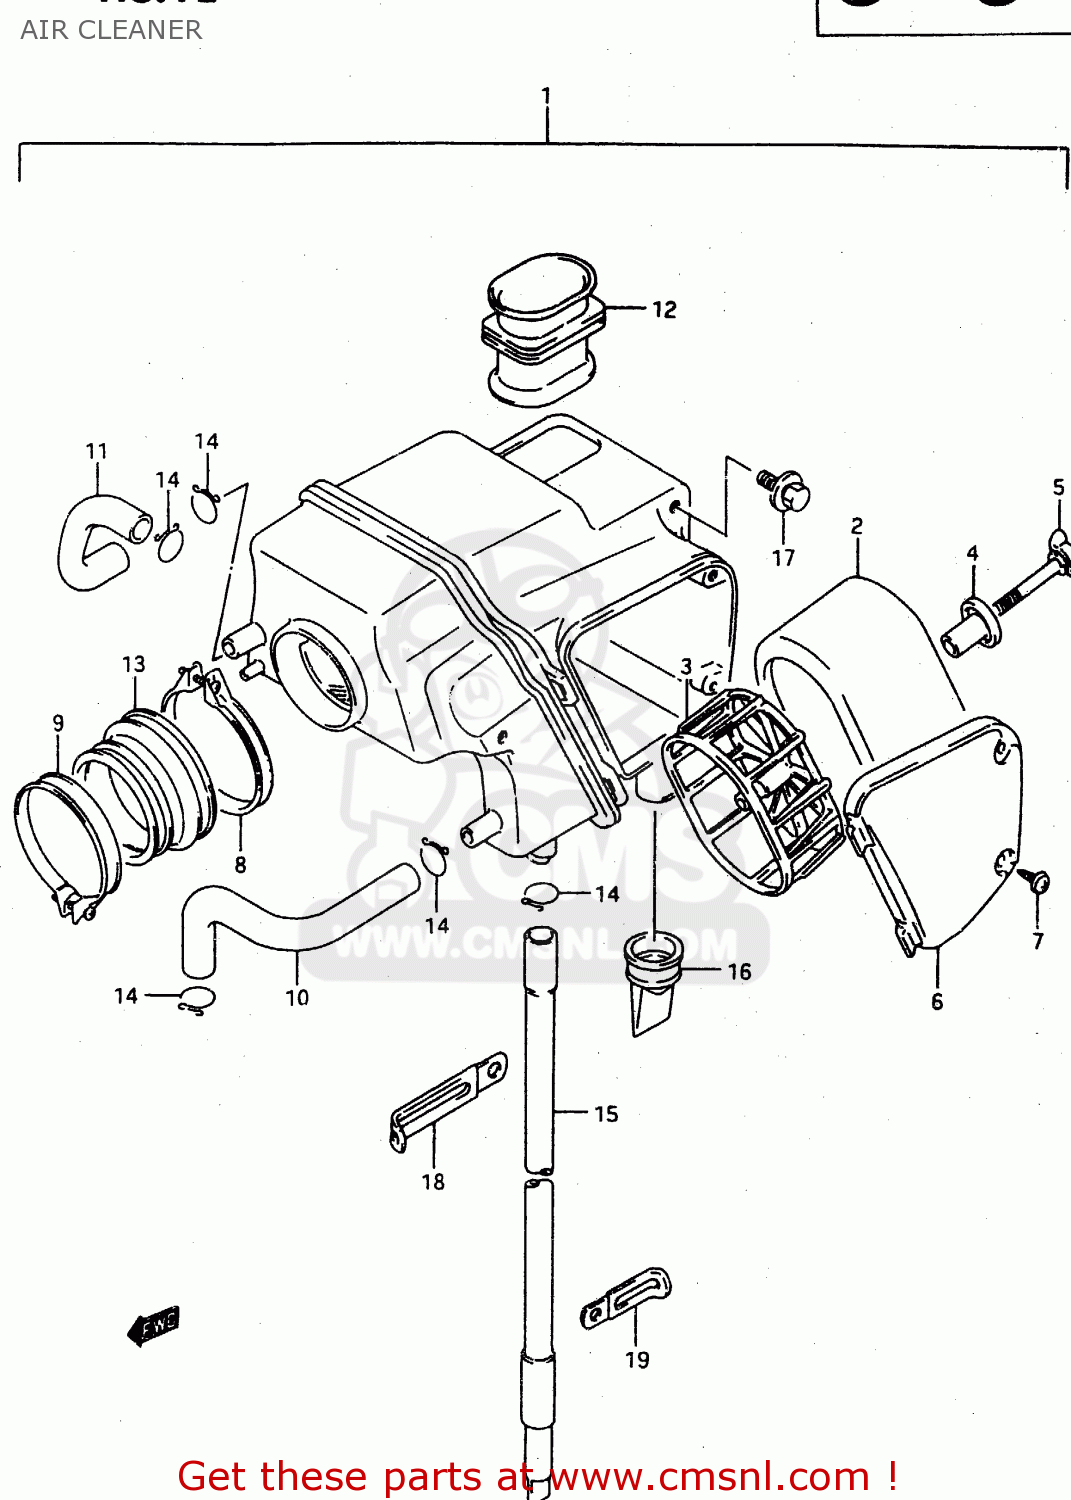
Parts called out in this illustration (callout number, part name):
1	CLEANER ASSY,AIR
2	FILTER
3	HOLDER,FILTER
4	SPACER
5	BOLT, WING
6	CAP,AIR CLEANER
7	SCREW
8	CLAMP
9	CLAMP
10	TUBE,BREATHER
11	TUBE,CONNECTING
12	TUBE,INLET
13	TUBE,OUTLET
14	CLIP
15	DRAIN TUBE
16	CAP,DRAIN
17	BOLT(6X14)
18	CLAMP
19	CLAMP
